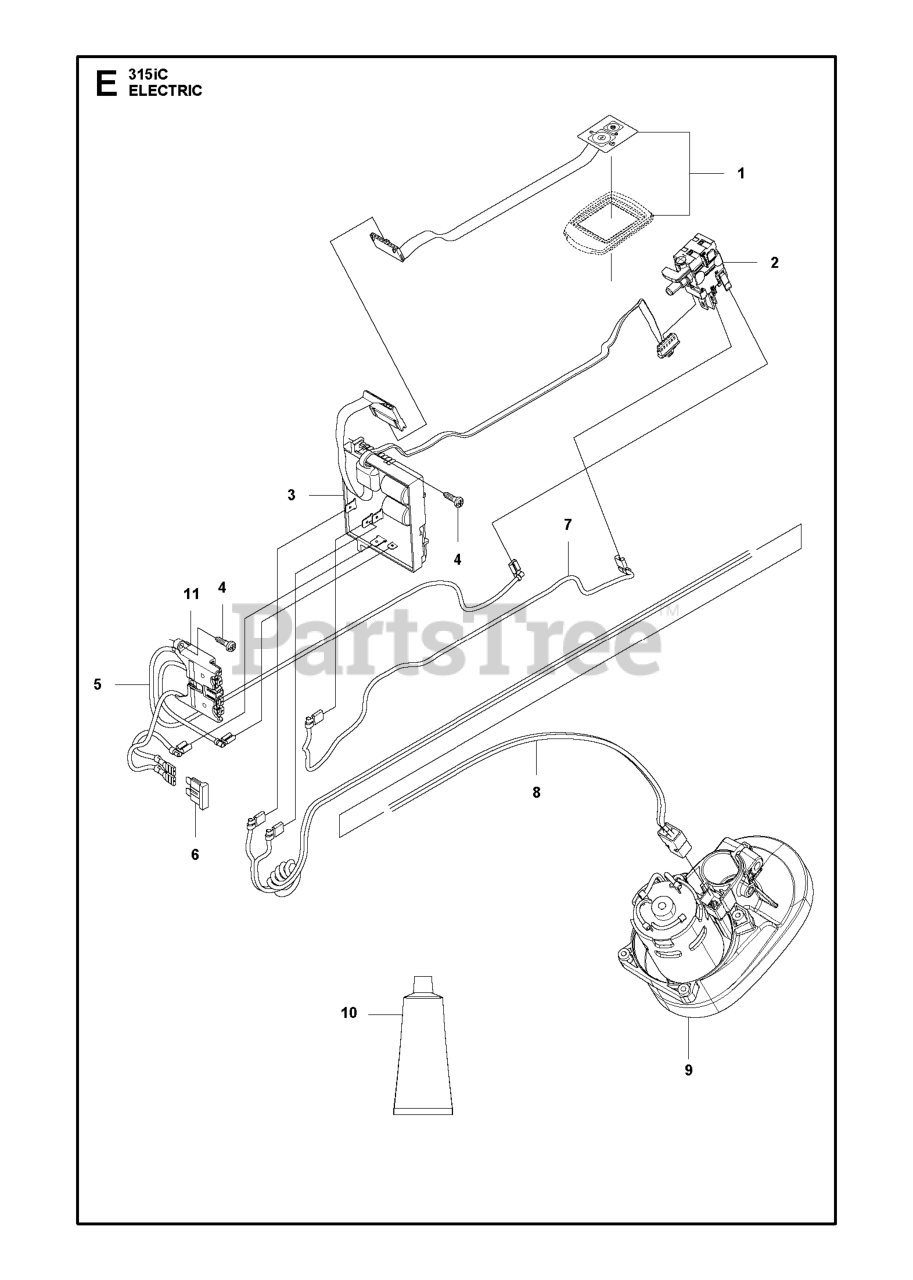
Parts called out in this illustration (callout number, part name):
2	TRIGGER SWITCH
3	DC MOTOR CONTROLLER ASSY
5	WIRING ASSY
7	WIRING ASSY
8	WIRING ASSY
10	GREASE TUBE Q8 RUYSDAEL WR2
11	CONNECTOR BATTERY
